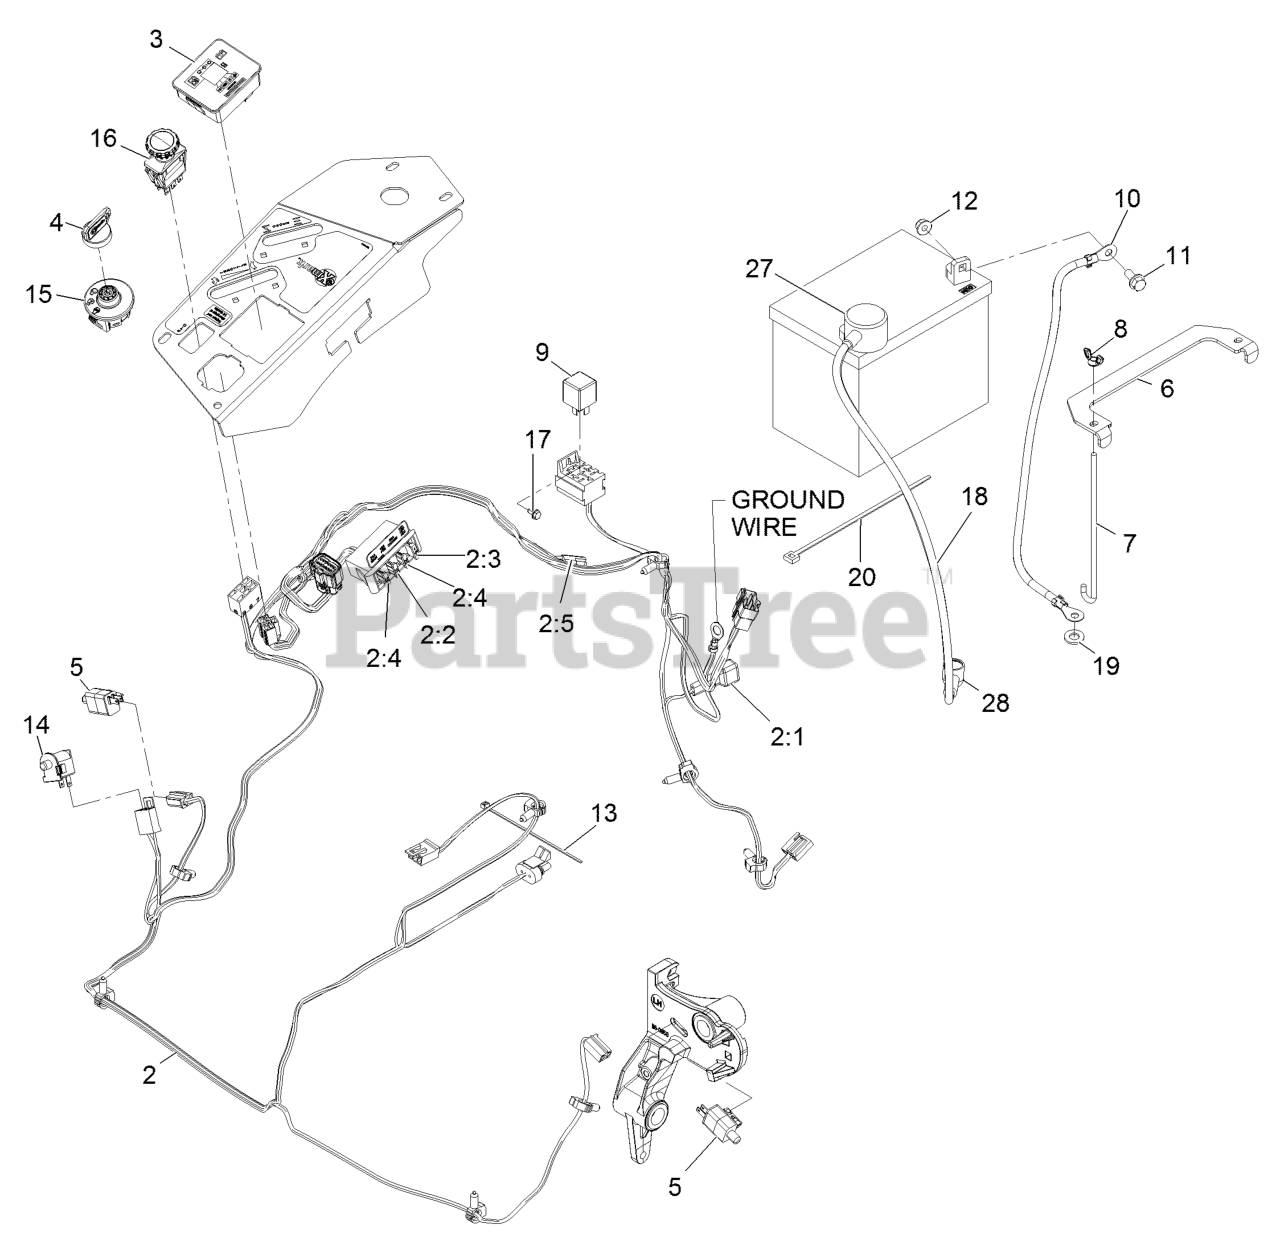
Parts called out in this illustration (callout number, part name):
2	HARNESS-WIRE, MAIN
2:2	FUSE-BLADE, 10 AMP
2:3	FUSE-BLADE, 15 AMP
2:4	FUSE-BLADE, 25 AMP
2:5	CAP-PLUG
3	FUEL/HOUR METER ASM
4	KEYS-IGNITION (SPARE PAIR
4	KEY-IGNITION
6	STRAP-TIE DOWN, BATTERY
7	BOLT-HOLDDOWN
8	WINGNUT
10	CABLE-BATTERY, NEGATIVE
11	SCREW-HHF
12	NUT-HF, NI
13	TIE-CABLE
14	SWITCH-BAIL
16	SWITCH-PTO, 10 AMP
17	SCREW-HWH
18	CABLE-BATTERY, POSITIVE
19	WASHER-FLAT
20	TIE-PLASTIC
27	INSULATOR-BATTERY
28	INSULATOR-SOLENOID
